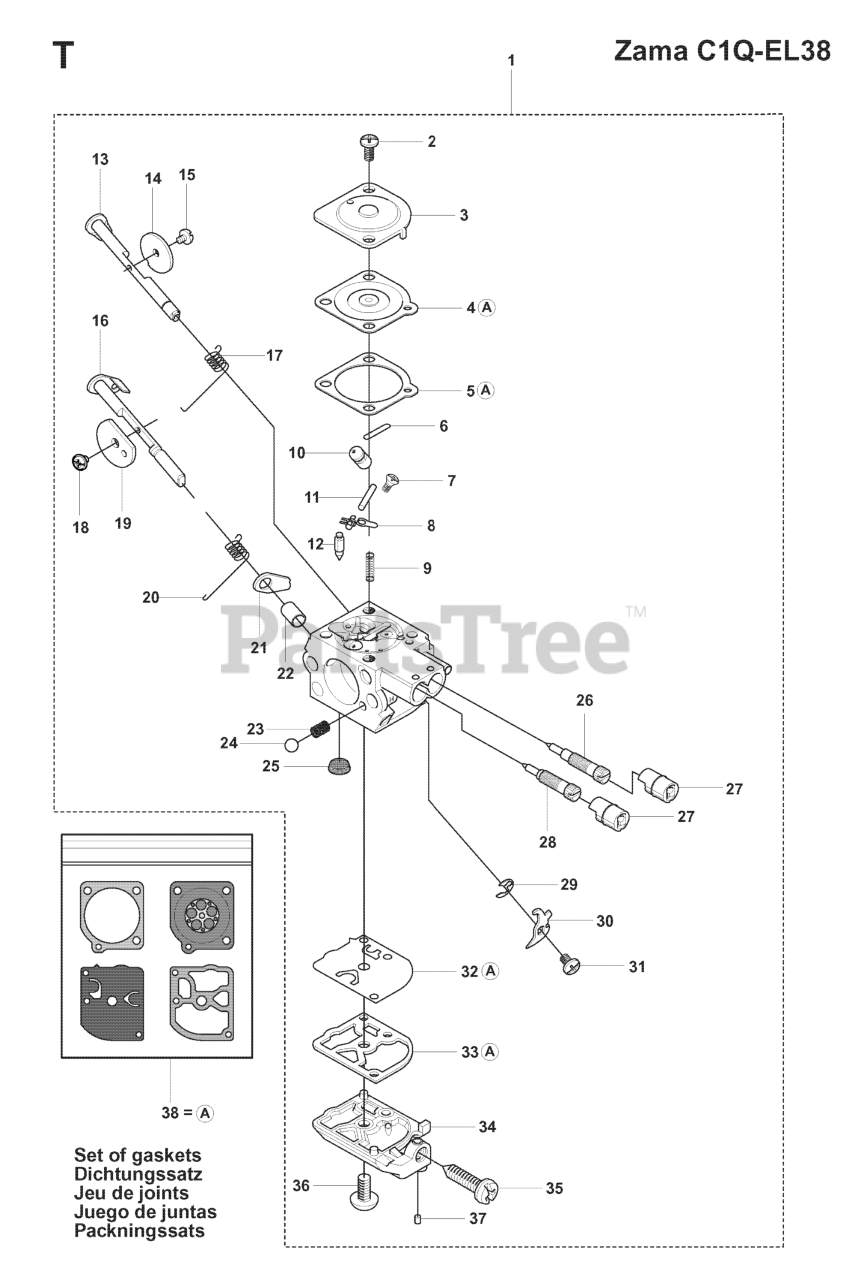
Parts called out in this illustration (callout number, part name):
1	CARBURETTOR C1Q-EL38
9	SPRING
11	PIN RETAINING SCREW
12	INLET NEEDLE
13	SHAFT ASSY
16	SHAFT ASSY
17	RETURN SPRING
25	FUEL INLET SCREEN
26	IDLE SCREW
27	LIMITER CAP KIT
32	PUMP DIAPHRAGM
38	GASKET KIT (ZAMA GND39)
